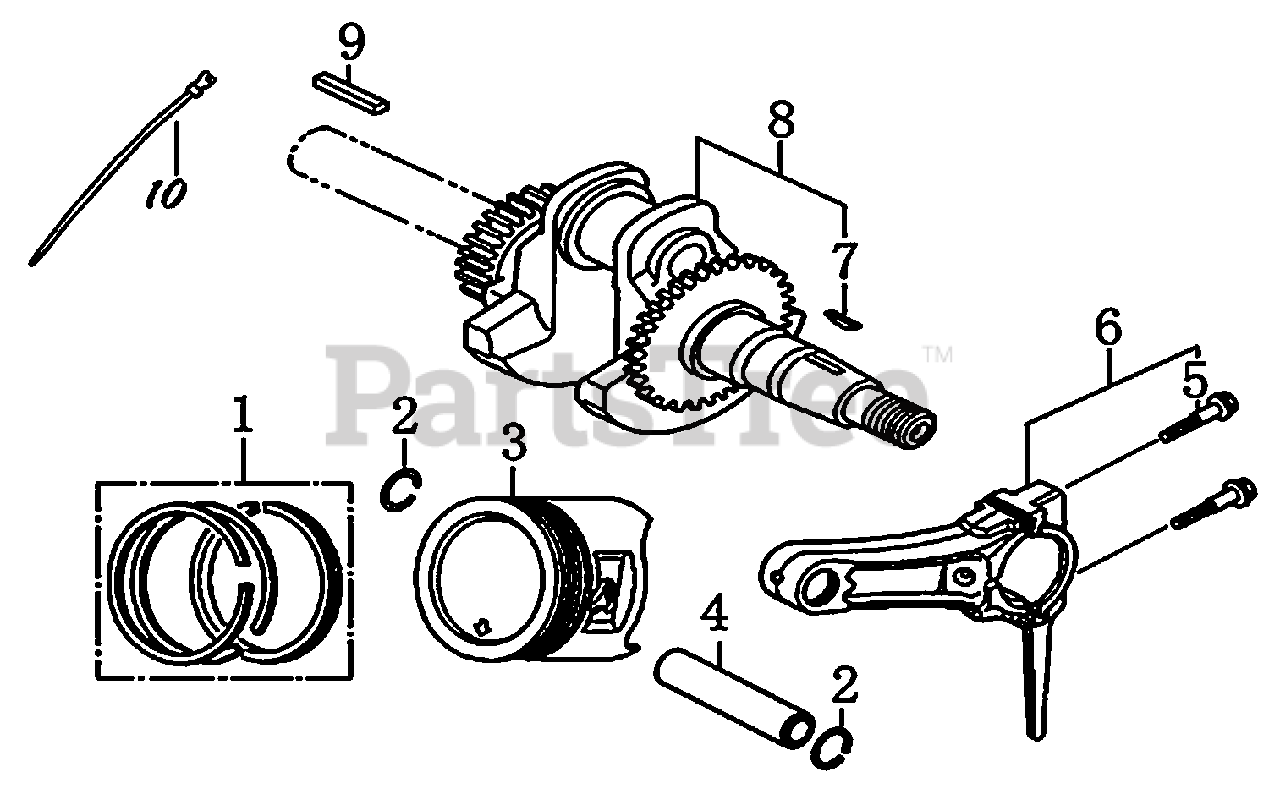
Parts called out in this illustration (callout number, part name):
2	CLIP, PISTON PIN
4	PIN, PISTON
5	BOLT, CONNECTING ROD
6	ROD ASSY., CONNECTING
8	CRANKSHAFT COMP
10	ZIP TIE
